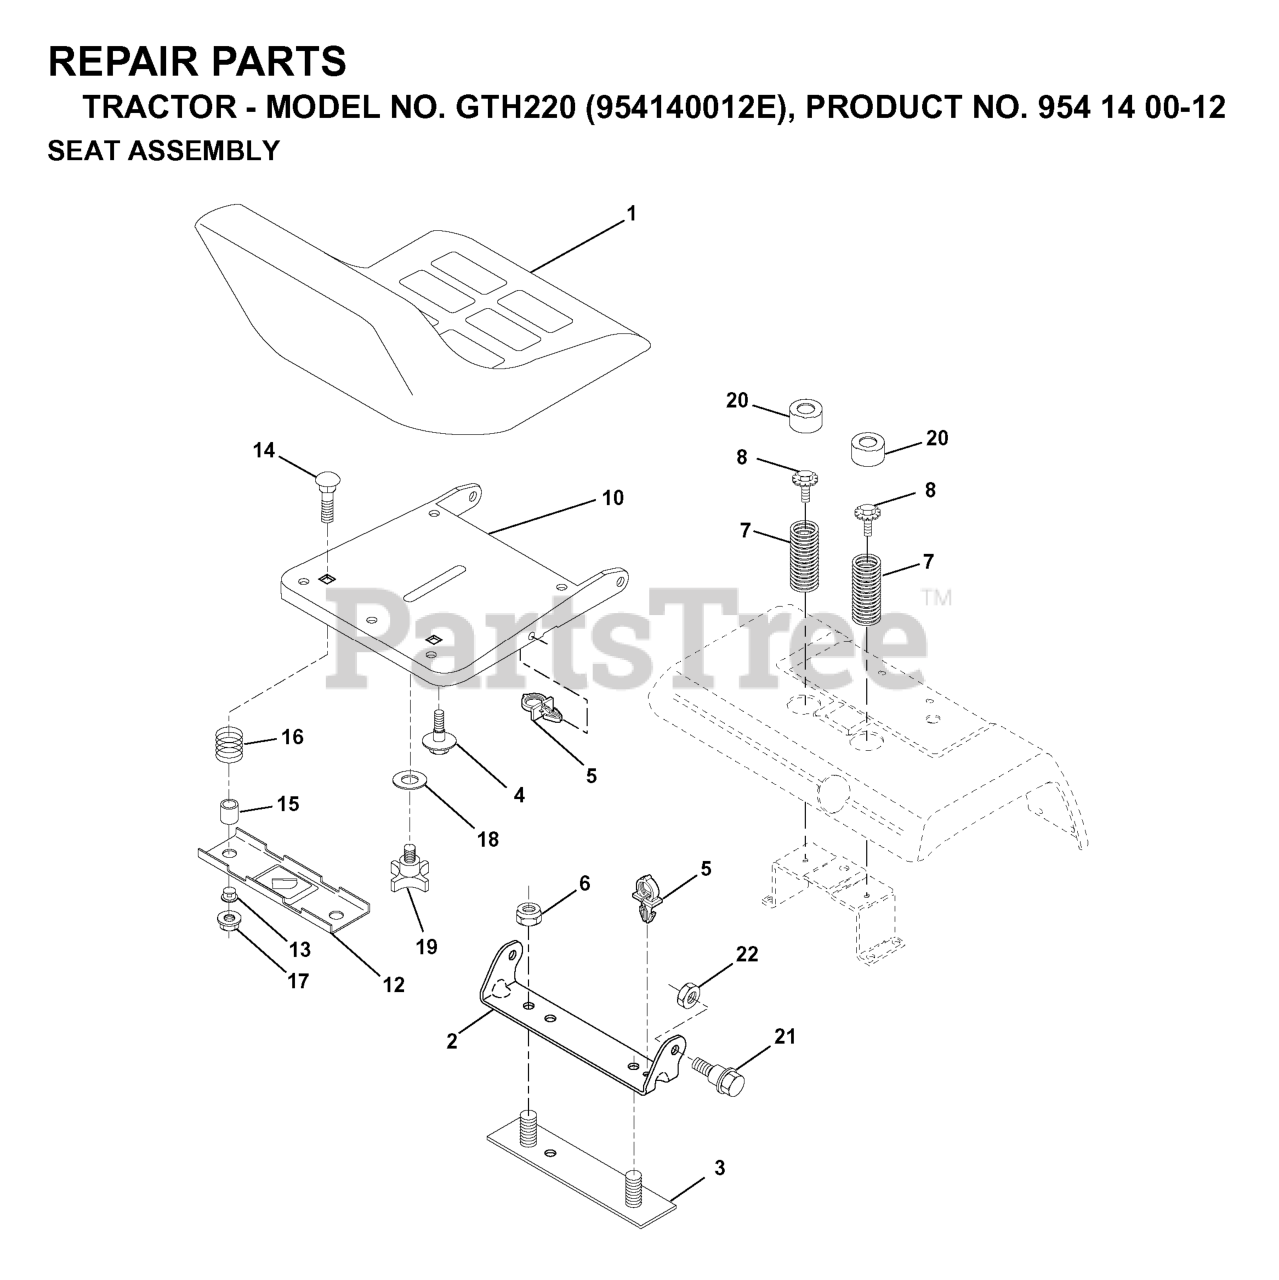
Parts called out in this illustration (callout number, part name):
1	SEAT
2	SEAT PIVOT BRKT
3	STRAP
4	BOLT,SHOULD
6	NUT
7	SPRING COMPRESSION
8	BOLT HEX WASHER HD 5/16-18
10	PAN, SEAT
12	BRKT SWITCH
14	BOLT.ROUND.HEAD.SQUARE.NECK
15	SPACER SPLIT
16	SPRING COMPRESSED
17	NUT T
19	KNOB 1/2" YT
20	CAP SPRING
21	BOLT SHOULDER 5/16-18
22	LOCKNUT
